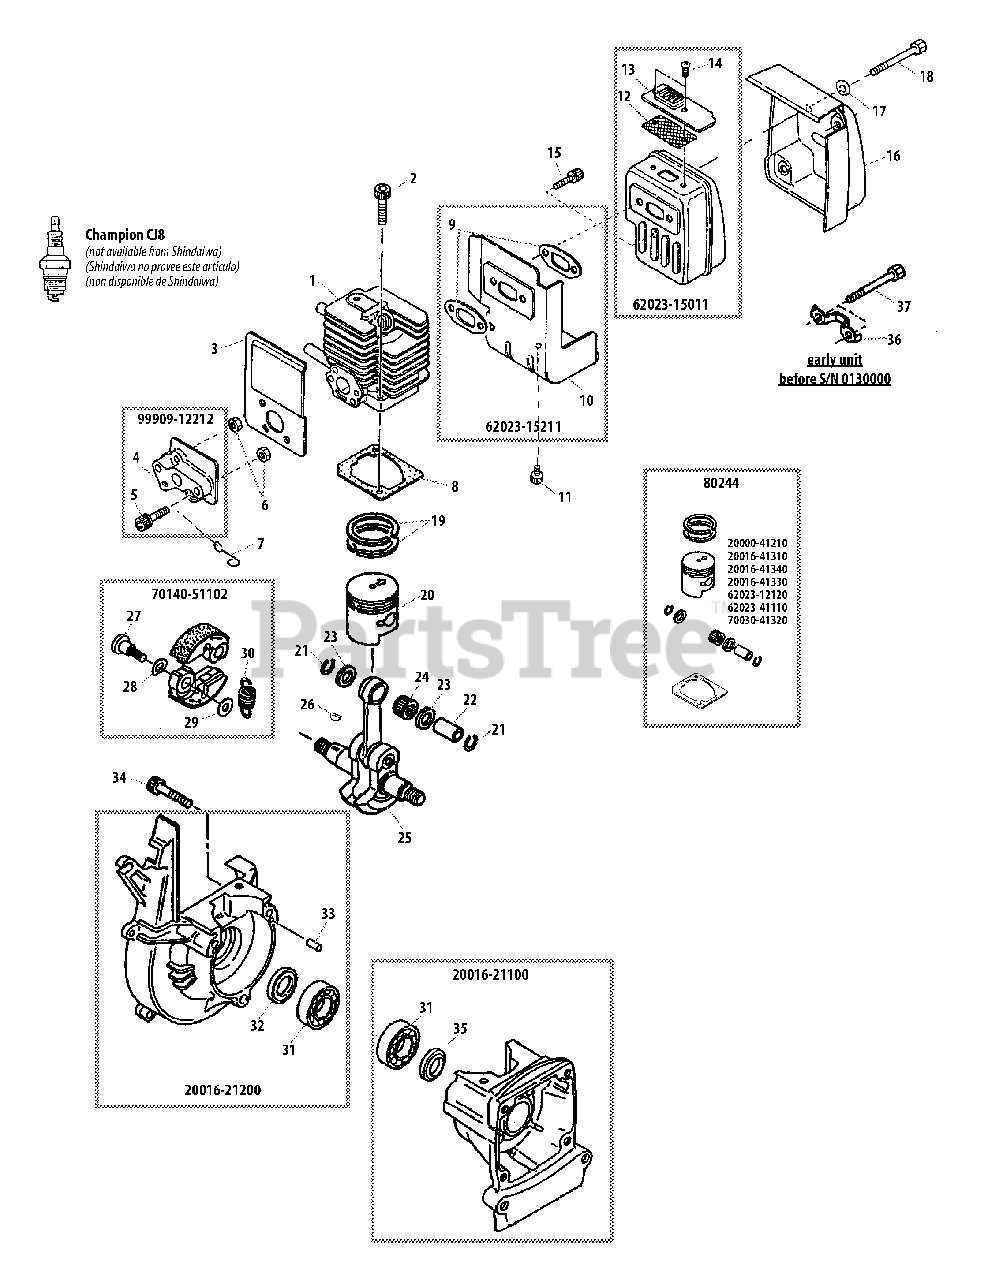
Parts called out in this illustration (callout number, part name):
1	CYLINDER
2	BOLT 5×25
3	HEAT SHIELD, INTAKE
4	INSULATOR
5	BOLT SS M5×30
6	NUT M5×6.3
7	CLIP, VENT ASSY
8	GASKET, CYLINDER
9	GASKET, EXHAUST
11	BOLT 5×8
12	SCREEN, SPARK ARRESTER
13	OUTLET, EXHAUST
14	SCREW M4×6
15	BOLT 5×20
16	COVER, EXHAUST
17	PLATE, LOCK
19	RING, PISTON
20	PISTON
21	RING, SNAP
22	PIN, PISTON
23	WASHER, THRUST
24	BEARING, NEEDLE
25	CRANKSHAFT
26	KEY, WOODRUFF 3×10
27	BOLT, CLUTCH
28	WASHER, SPRING
29	WASHER 6 MM
30	SPRING, CLUTCH
31	BEARING, BALL 6001 C3
32	SEAL, OIL 12
33	PIN, LOCATING Ø4×8
34	BOLT 5×25
35	SEAL, OIL 12
20016-21100	CRANKCASE ASSY, S
20016-21200	CRANKCASE ASSY, M
62023-15011	MUFFLER ASSY
62023-15211	DEFLECTOR ASSY, EXHAUST HEAT
70140-51102	CLUTCH ASSY
80244	PISTON ASSY
99909-12212	INSULATOR ASSY
